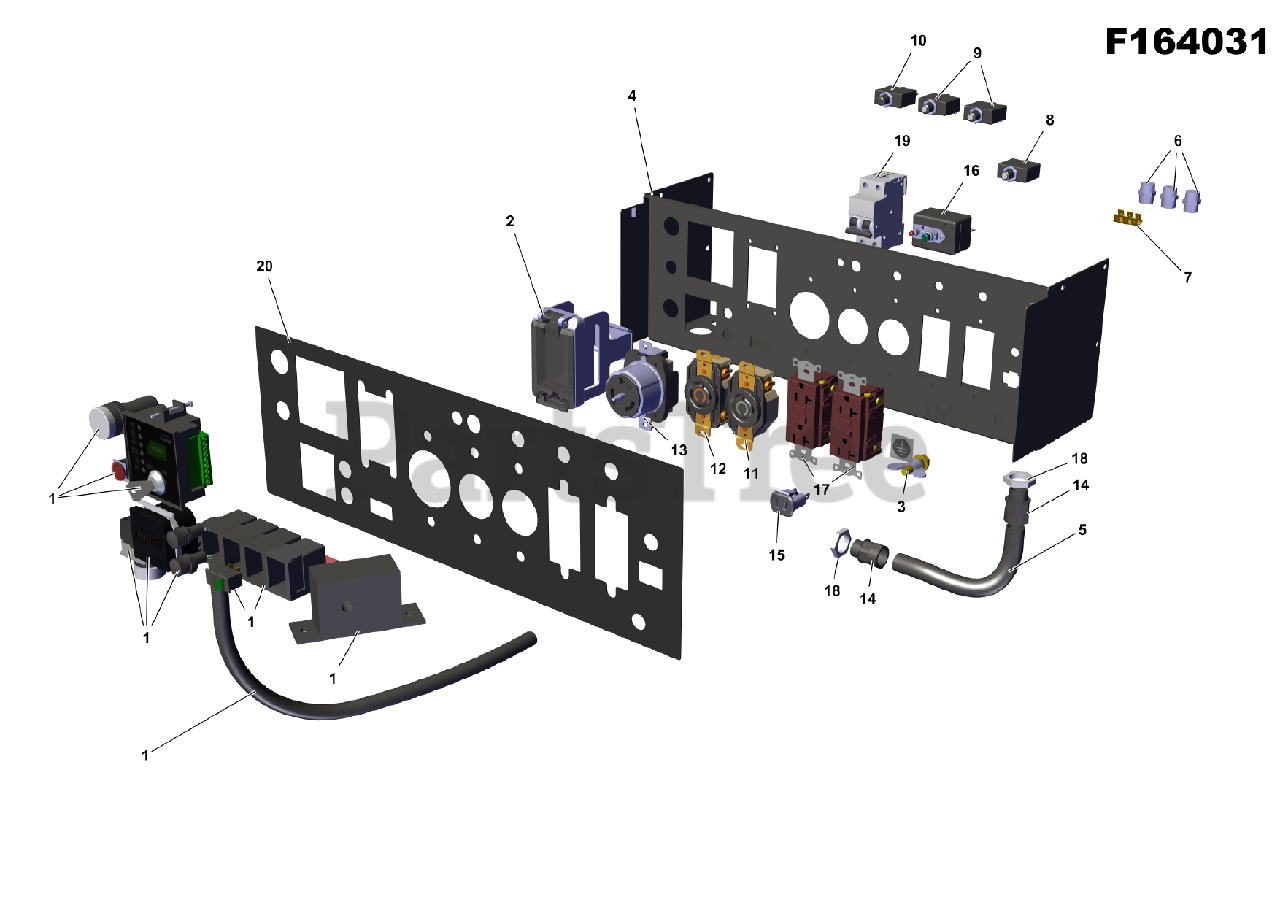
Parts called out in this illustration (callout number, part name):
1	See-Engine wiring harness assembly
2	See-Plastic Window
3	See-Screws assembly
6	Insulator
8	CIRCUIT BREAKER
9	CIRCUIT BREAKER
10	Circuit breaker 1x230A
11	RECEPTACLE, NEMA L5-30R SOCKET
12	RECEPTACLE, NEMA L14-30R 4P SOCKET
13	Socket base 250V-050A-2P T N
14	Pipe union PG16
15	RECEPTACLE, DC SOCKET 12V8.3A
16	Circuit breaker 2x32A
17	RECEPTACLE, GFCI 20A/125V NEMA 5-20OR
19	Modular circuit breaker 2x50A
20	Sticker PRO12.3EFI
